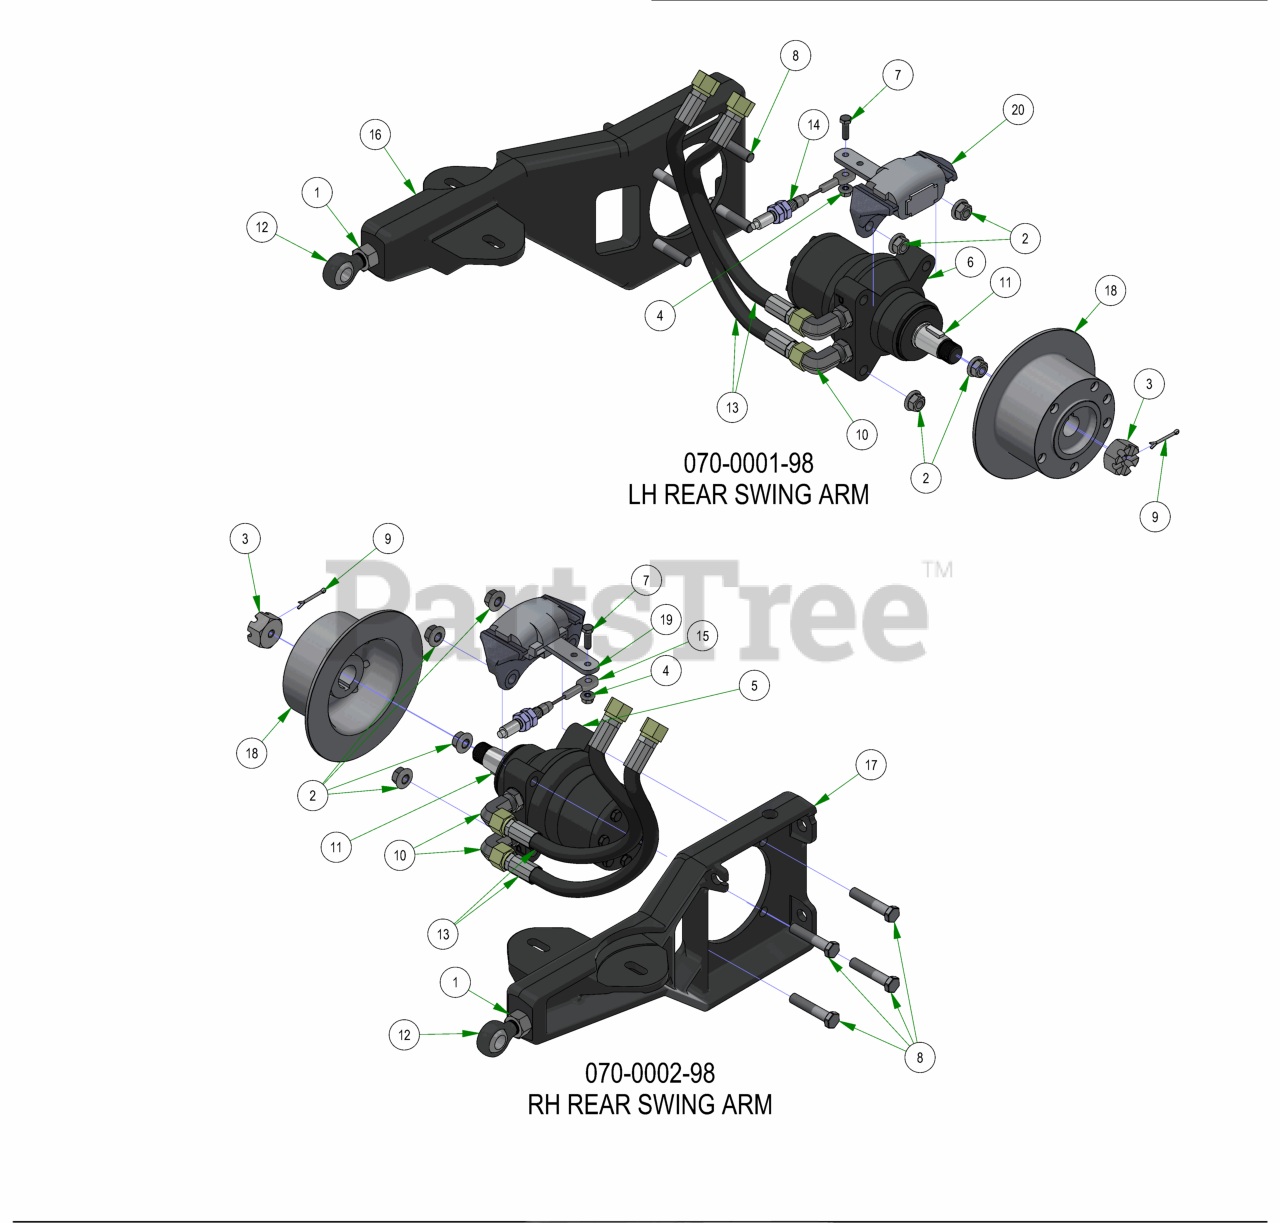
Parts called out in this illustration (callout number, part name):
1	3/4"-16 Fine Full Nut
2	1/2-13 Gr 8 Centerlock Flange Nut
3	1" Castle Nut for HydroGear Wheel Motor
4	5/16-18 NYLON INSERT FLANGE LOCKNUT ZINC
5	18cc Parker Wheel Motor- Right
6	18cc Parker Wheel Motor- Left
7	5/16-18 X 1 HEX CAP SCREW (GR.5) ZINC
8	1/2-13 x 2.75 Gr. 8 Hex Head Bolt
9	1/8 X 1-1/2 COTTER PIN ZINC
10	2019 Rouge/Renegade Wheel Motor 90* Fitting #6801-10L
11	Woodruff Key
12	3/4-16 RH Male Rod End
13	20" Hydraulic Hose
14	2019 Short Brake Cable-Suspension Models
15	2019 Long Brake Cable-Renegade, Rogue
16	2019 Left Trailing Arm
17	2019 Right Trailing Arm
18	Brake Disk
19	XP/AOS Right Brake Caliper
20	XP/AOS Left Brake Caliper
